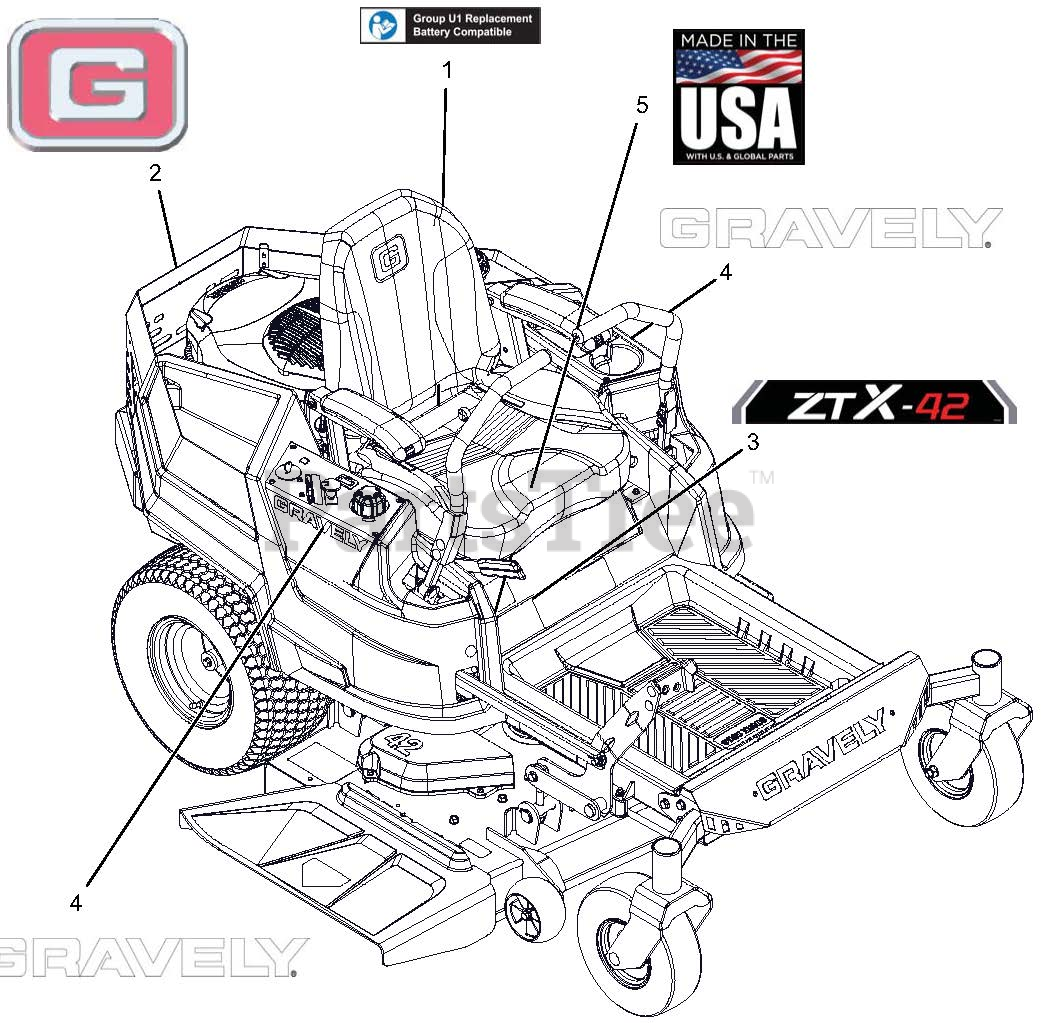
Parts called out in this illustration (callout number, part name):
1	DECAL, U1 BATTERY REPLACEMENT
2	DECAL, GRAVELY BRAND
3	DECAL, GRAVELY ZT X 42
4	DECAL, 9.5" GRAVELY LOGO
5	DECAL, MADE IN USA
